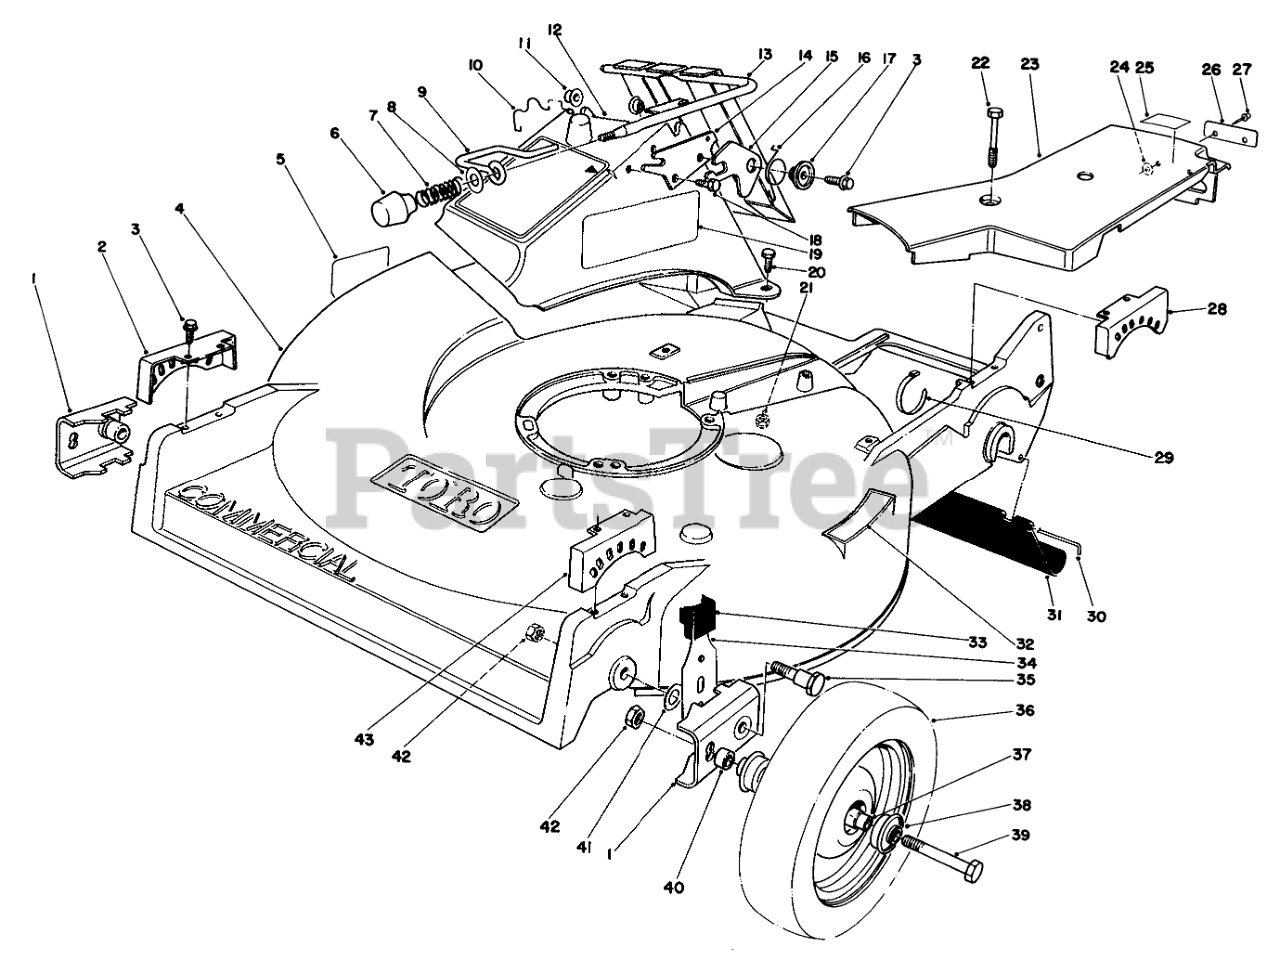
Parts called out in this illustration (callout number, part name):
1	PIVOT ARM
2	QUADRANT-FRONT, RH
3	Screw
4	Housing-Commercial (Incl. Ref. #5 & 32)
5	DECAL-DANGER
7	COMPRESSION SPRING
8	WASHER-FLAT
9	DOOR LATCH
10	DOOR RETAINER
11	BUSHING-NYLON
12	Chute & Door Assy. (Incl. Ref. #3, 6-11 & 13-21)
13	DOOR & HANDLE WA
14	DOOR LATCH PLATE
15	SAFETY LATCH
16	TORSION SPRING
17	DOOR SPACER
18	SCREW-HWH
19	DECAL SAF INST
20	SCREW-HH
21	NUT-LOCK, NI
22	SCREW-HHFTF
23	Belt Cover Assembly (Incl. Ref. #24, 26-27)
24	WASHER-PLAIN
25	Label-Grease
26	NAMEPLATE-GRD SPEED
28	QUADRANT-REAR, LH
29	TIE-CABLE
30	ROD-SHIELD
31	SHIELD-TRAILING
32	STEP PAD DECAL
33	KNOB-ARM
34	SPRING ARM ASM-FRONT
35	PIVOT SCREW
36	Wheel & Tire Assembly (Incl. Ref. #37, 38)
37	SPACER-BEARING
38	BEARING-WHEEL
39	SCREW-HH
40	SPACER-WHEEL
41	WASHER-PIVOT
42	NUT-LOCK, NI
43	QUADRANT-FRONT, LH
